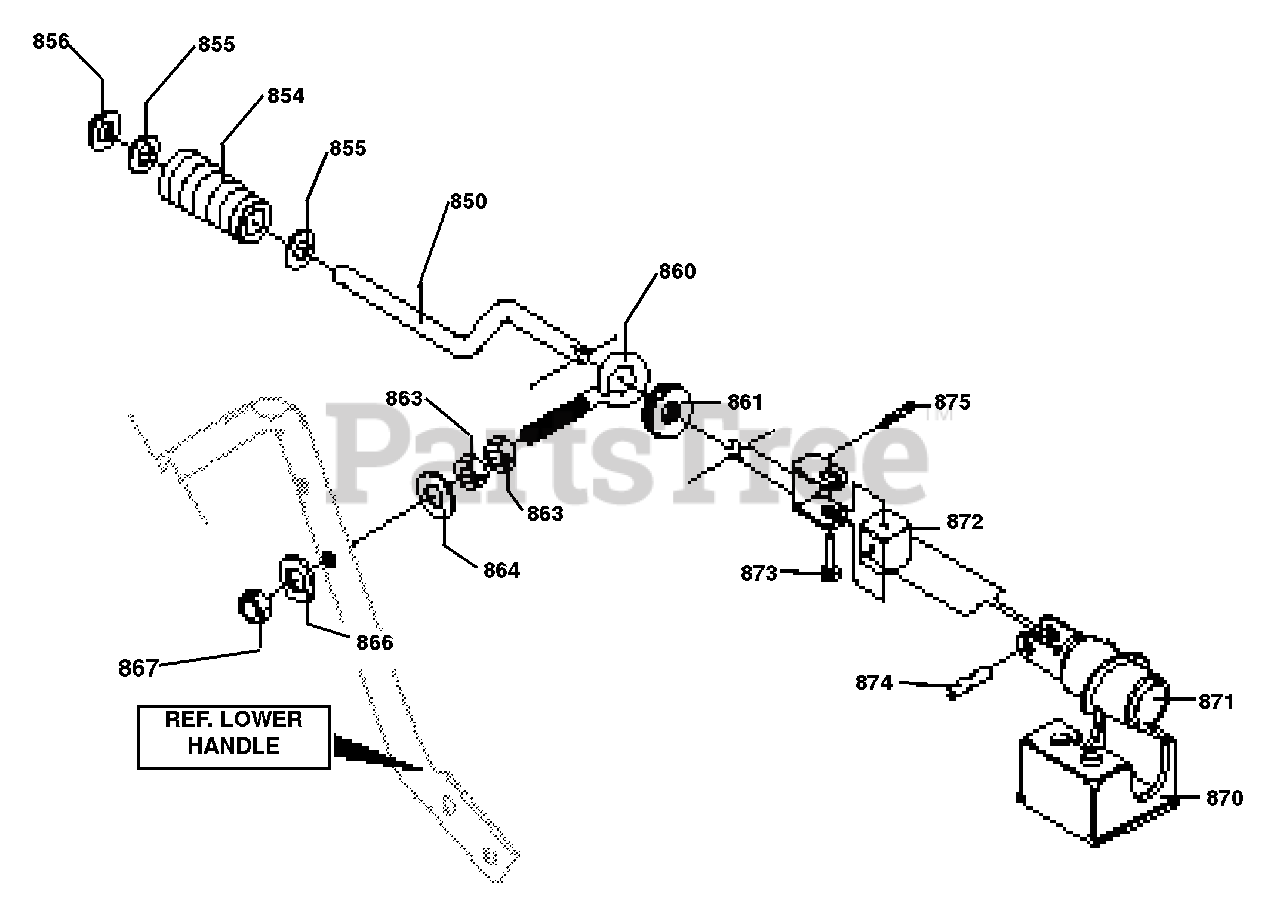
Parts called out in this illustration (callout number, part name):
850	CRANK, ASSY
855	WASHER, FLAT .439 X .70 X .05
861	GROMMET, EYE BOLT
863	NUT, 3/8-16
864	WASHER, FLAT .406 X .81 X .065
866	WASHER, FLAT .406 X .81 X .065
867	NUT, 3/8-16
870	BRKT, WORM
871	WORM, GEAR CHUTE
872	BLOCK, UNIV PIV
873	PIN, CLEVIS
874	PIN, UNIV JOINT
875	PIN, COTTER
